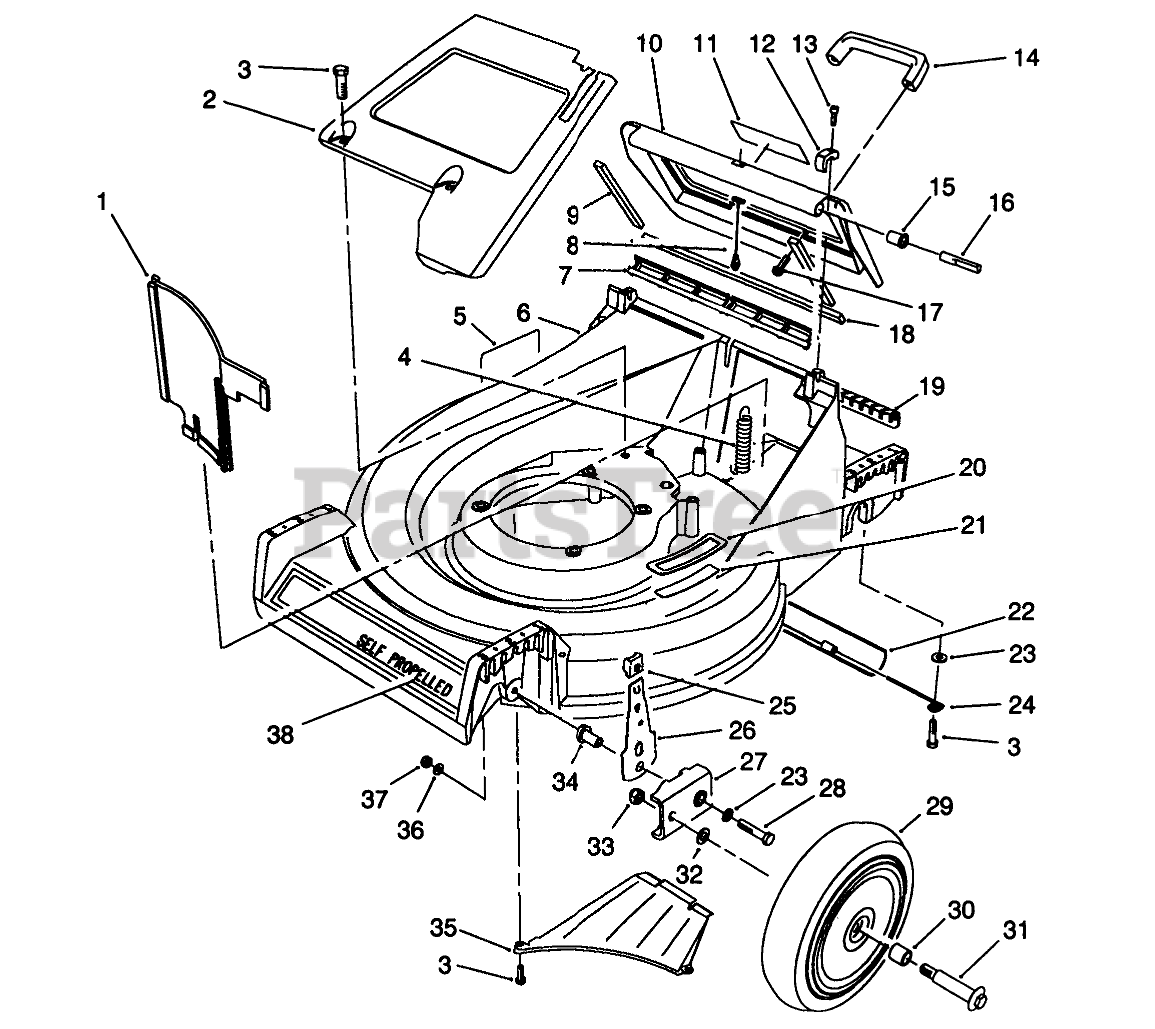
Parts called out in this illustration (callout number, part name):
1	PANEL-VERTICAL
2	PaneI-Screen
3	SCREW-HWHTF
4	EXTENSION-SPRING
5	DECAL-DANGER
6	Housing-21"
7	DOOR SEAL
8	DOOR CABLE
9	DOOR SIDE SEAL
10	Door-Discharge
11	DECAL - WARNING
12	HINGE CLAMP
13	SCREW-HSH
14	HANDLE-DOOR
15	DOOR BUSHING
16	HINGE PIN
17	SCREW-HWH
18	DOOR END SEAL
19	ACCESS COVER
20	STEP PAD
21	STEP PAD DECAL
22	TRAILING SHIELD
23	WASHER-FLAT
24	LH SHIELD HANGER
25	KNOB-ARM
26	Arm-Front Spring
27	HP PIVOT ARM ASM
28	SCREW-HH
29	Wheel & Tire Assembly (Incl. Ref. #30)
30	BUSHING
31	WHEEL BOLT
32	WASHER
33	Nut
34	BUSHING-FLANGE
35	Ramp Discharge
36	WASHER-BELLEVILLE
37	NUT-LOCK, NI
38	DECAL - 21" SP
